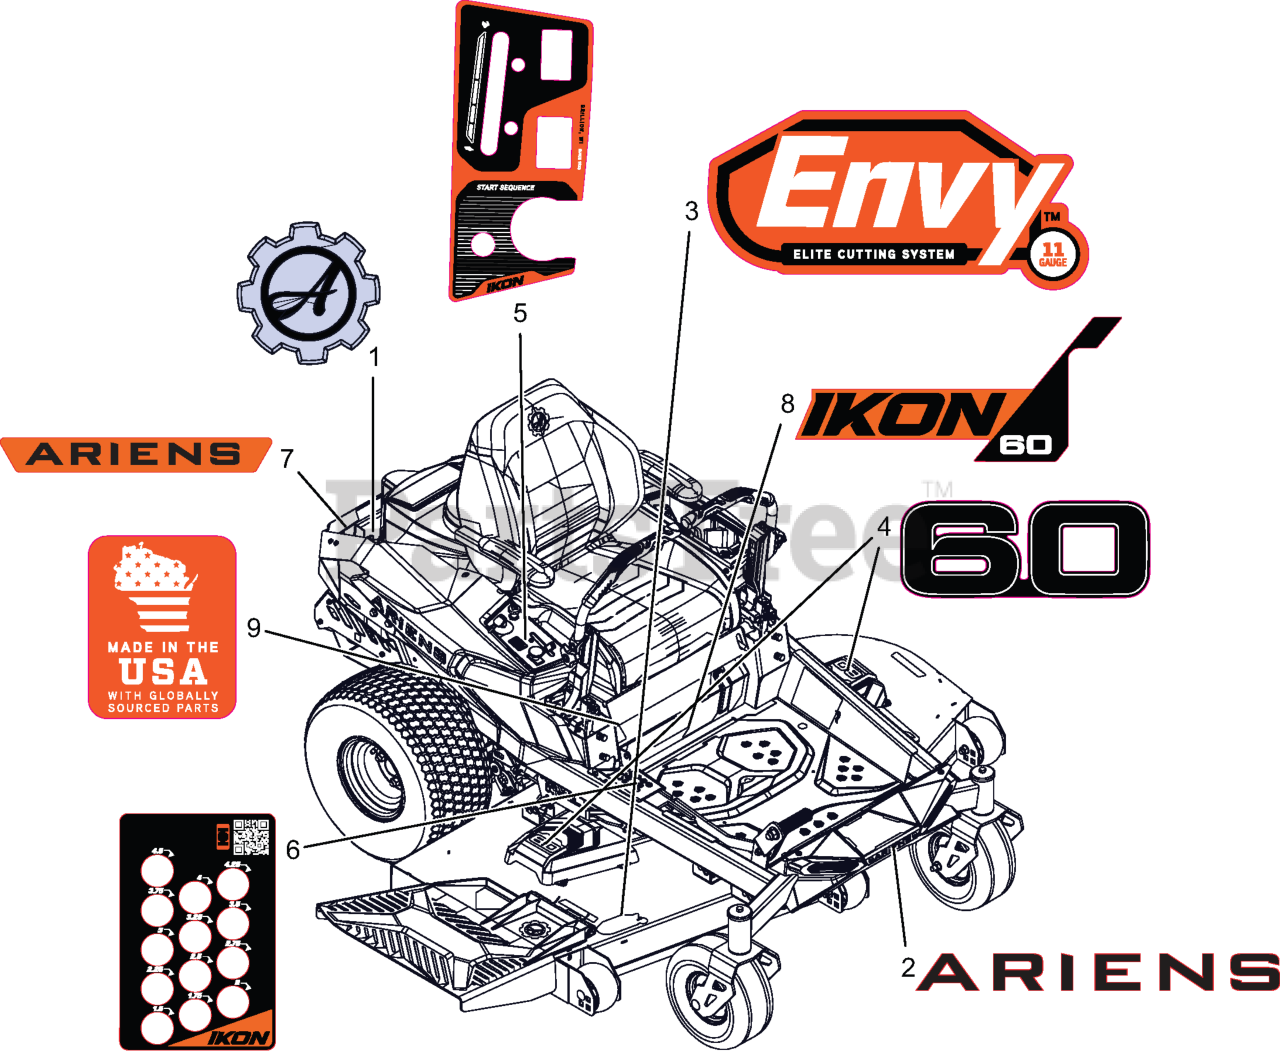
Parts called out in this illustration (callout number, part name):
1	DECAL- ARIENS GEAR BADGE
2	DECAL- ARIENS-BADGE
3	DECAL- DECK
4	DECAL- 60
5	DECAL- CONTROL PANEL
6	DECAL- HEIGHT OF CUT
7	DECAL- ARIENS
8	DECAL- IKON 60 KICKPLATE
9	DECAL- MADE IN USA
